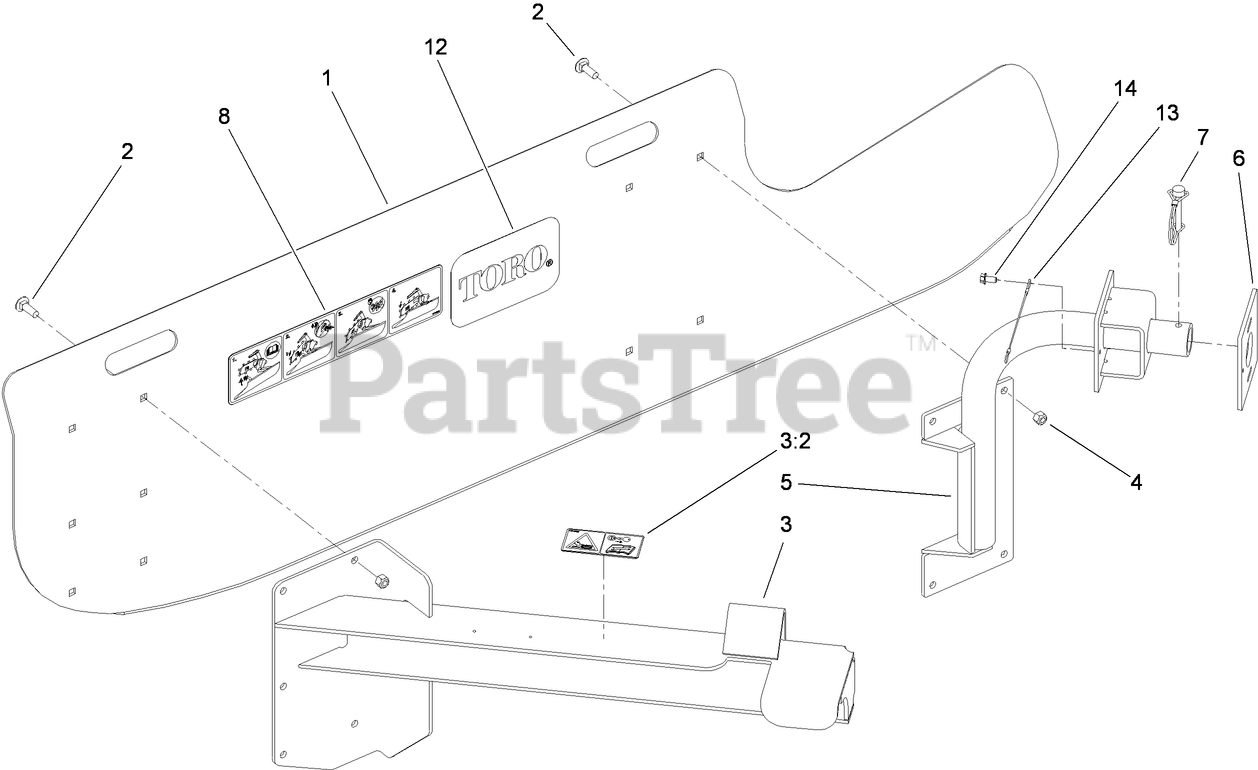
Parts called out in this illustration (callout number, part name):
1	PLATE-BLADE
2	BOLT-CARR
3	REAR MOUNT ASM
3:2	DECAL-WARNING
4	NUT-LOCK, NI
5	FRONT MOUNT ASM
6	PLATE-MOUNT
7	PIN-LOCKING
8	DECAL-INSTRUCTIONAL
12	DECAL
13	LANYARD
14	SCREW-HWH
